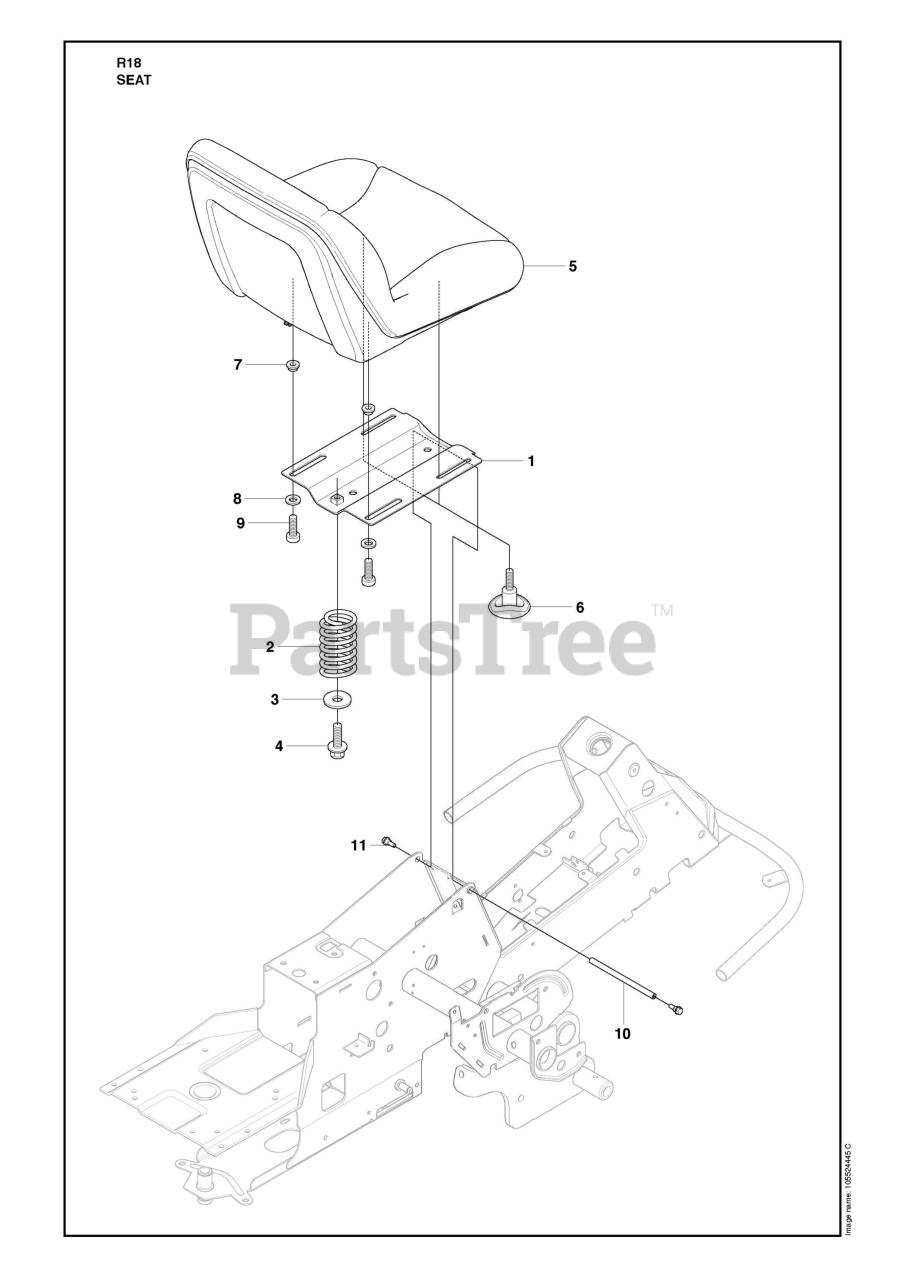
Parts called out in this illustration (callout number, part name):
1	SEAT BRACKET
2	SEAT SPRING
4	Screw, M10 X 25
5	SEAT
6	ADJUSTING KNOB
